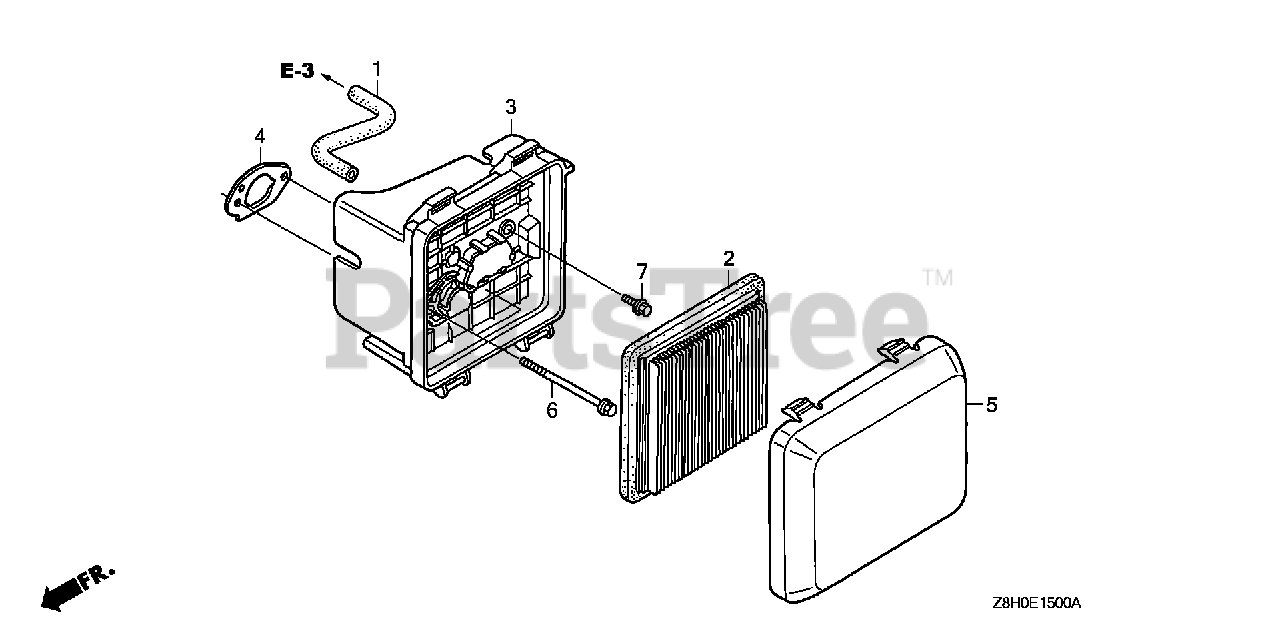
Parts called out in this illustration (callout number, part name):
1	TUBE, BREATHER
2	ELEMENT, AIR CLEANER
2	ELEMENT, AIR CLEANER (TOYO ROKI)
3	CASE ASSY., AIR CLEANER
4	GASKET, AIR CLEANER
5	COVER, AIR CLEANER
6	BOLT, FLANGE (6X86) (CT200)
7	BOLT, FLANGE (6X14)
